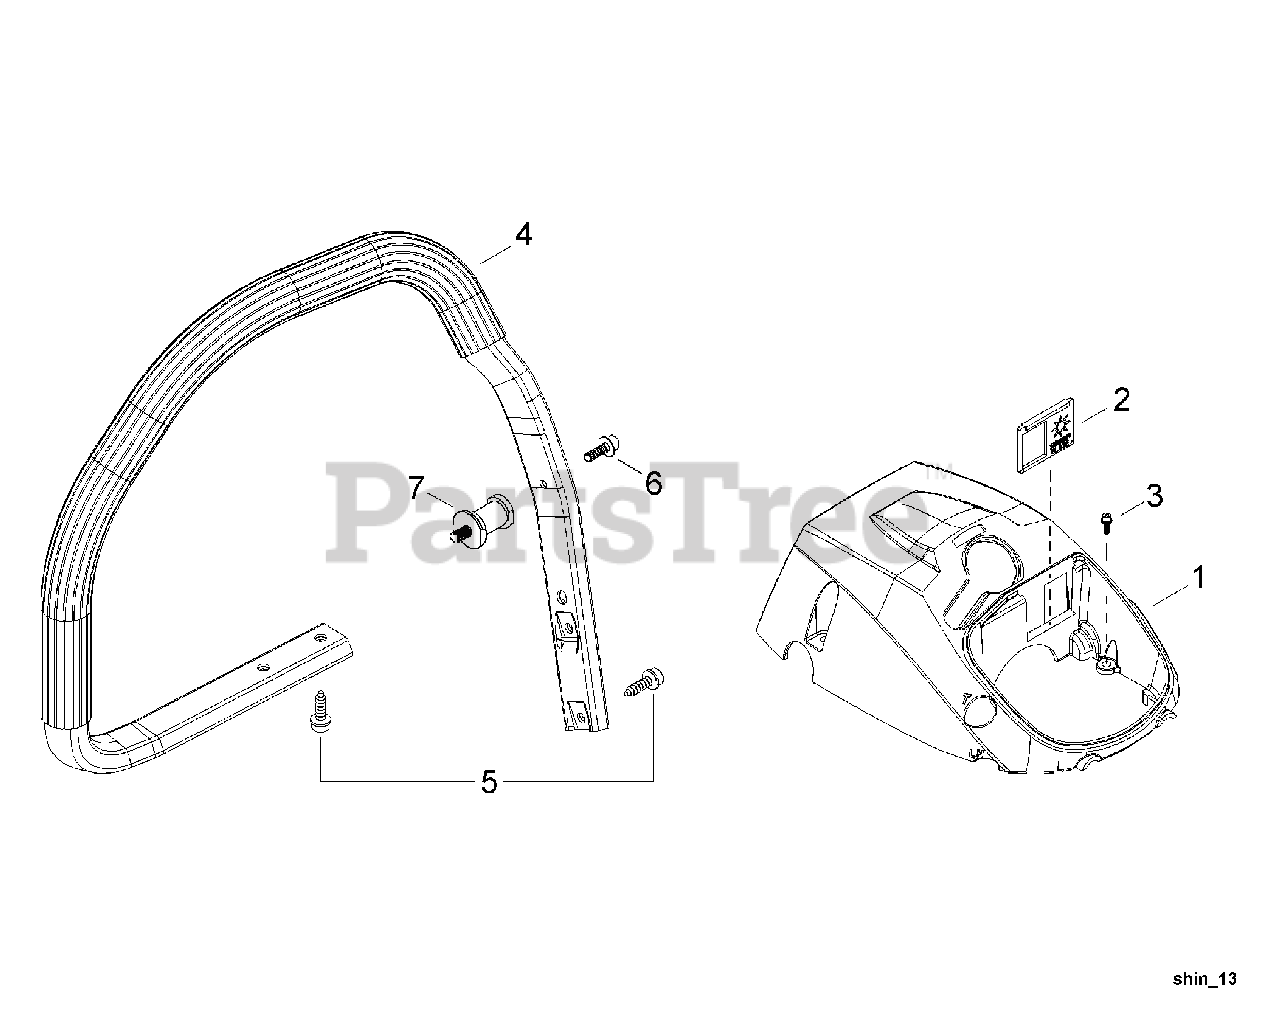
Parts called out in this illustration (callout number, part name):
1	COVER, ENGINE
2	PLATE, SHUTTER
3	BOLT M4×16
4	HANDLE, FRONT
5	BOLT, TAPPING M5×16
6	BOLT, ADHESIVE M4×14
7	CUSHION 5
